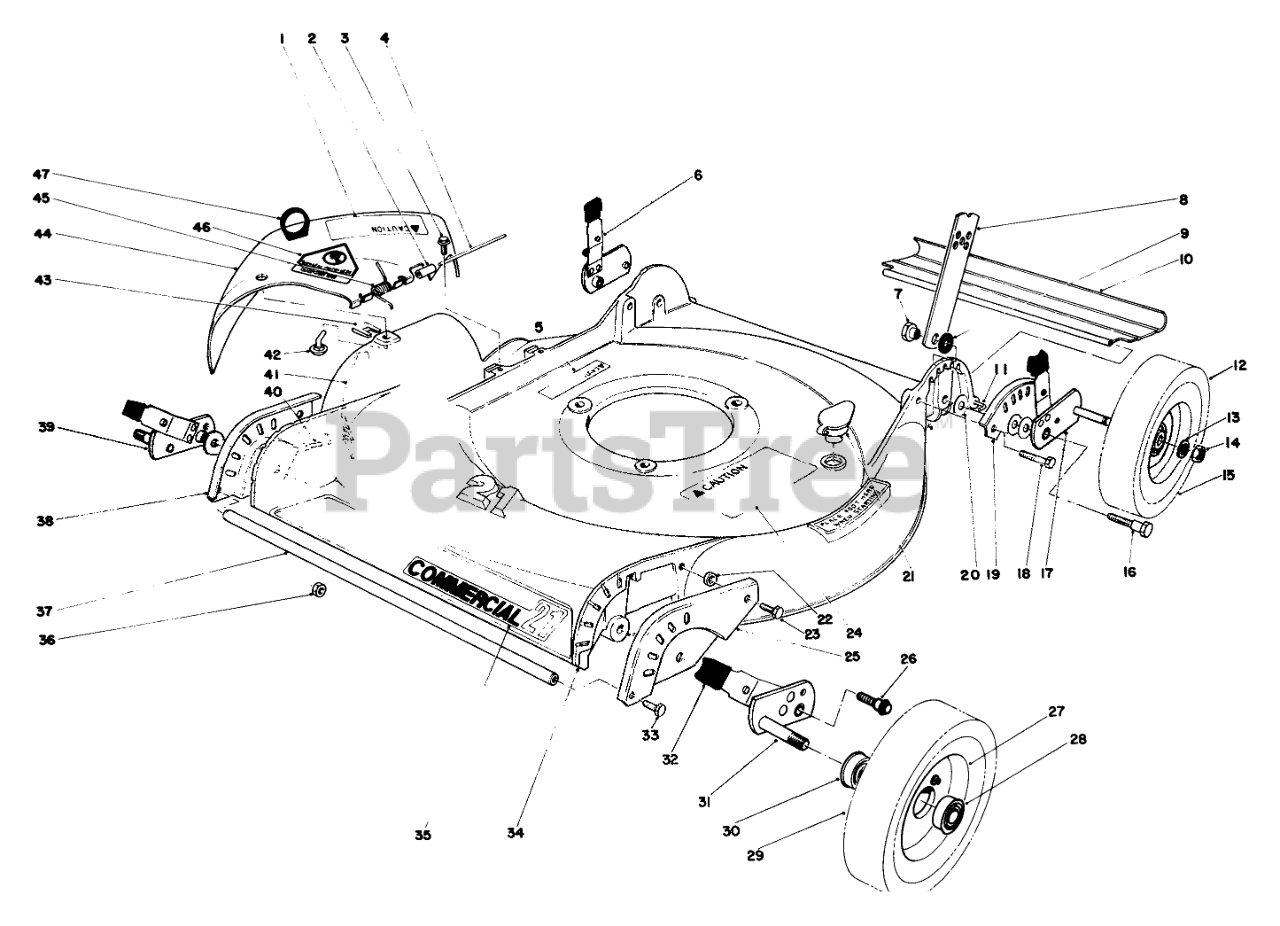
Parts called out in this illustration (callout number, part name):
1	DECAL DEFLECTOR
2	SLEEVE
3	SCREW
4	HINGE PIN
5	DECAL CAUTION
6	PIVOT ARM WA D
7	HANDLE PIVOT NUT
8	HANDLE LATCH
9	HANDLE LATCH SPACER
10	SHIELD - TRAILING
11	SHIELD ROD
12	Wheel Assembly (Incl. Ref. #15, 28 & 30)
13	FELT WASHER
14	NUT-LOCK, NI
16	PIVOT SCREW
17	Pivot Arm "B"
18	SCREW-HH
19	Wheel Quadrant L.H.
20	WASHER-PIVOT
21	WASHOUT PLUG
22	Spacer
23	SCREW-HWHTF
24	DECAL SAF INST
25	LH WHEEL QUAD FR
26	PIVOT SCREW
27	Wheel Assembly (Incl. Ref. #28-30)
28	BEARING
29	TIRE 7"
30	BEARING
31	Pivot Arm "C"
32	KNOB-ARM
33	SELF TAPPING SCREW
34	Housing (Incl. Ref. #5, 24 & 35)
35	COMMERCIAL DECAL
36	Nut
37	Bumper
38	RH WHEEL QUAD FRONT
39	PIVOT ARM WA A
40	SCREW THD 1/4 20 5/8
41	Bar Safety
42	BAG CHUTE PIN
43	BAG CHUTE CLIP PIN
44	Deflector (Incl. Ref. #1 & 46)
45	TORSION SPRING
46	DECAL-DANGER
47	LIFT LOOP
